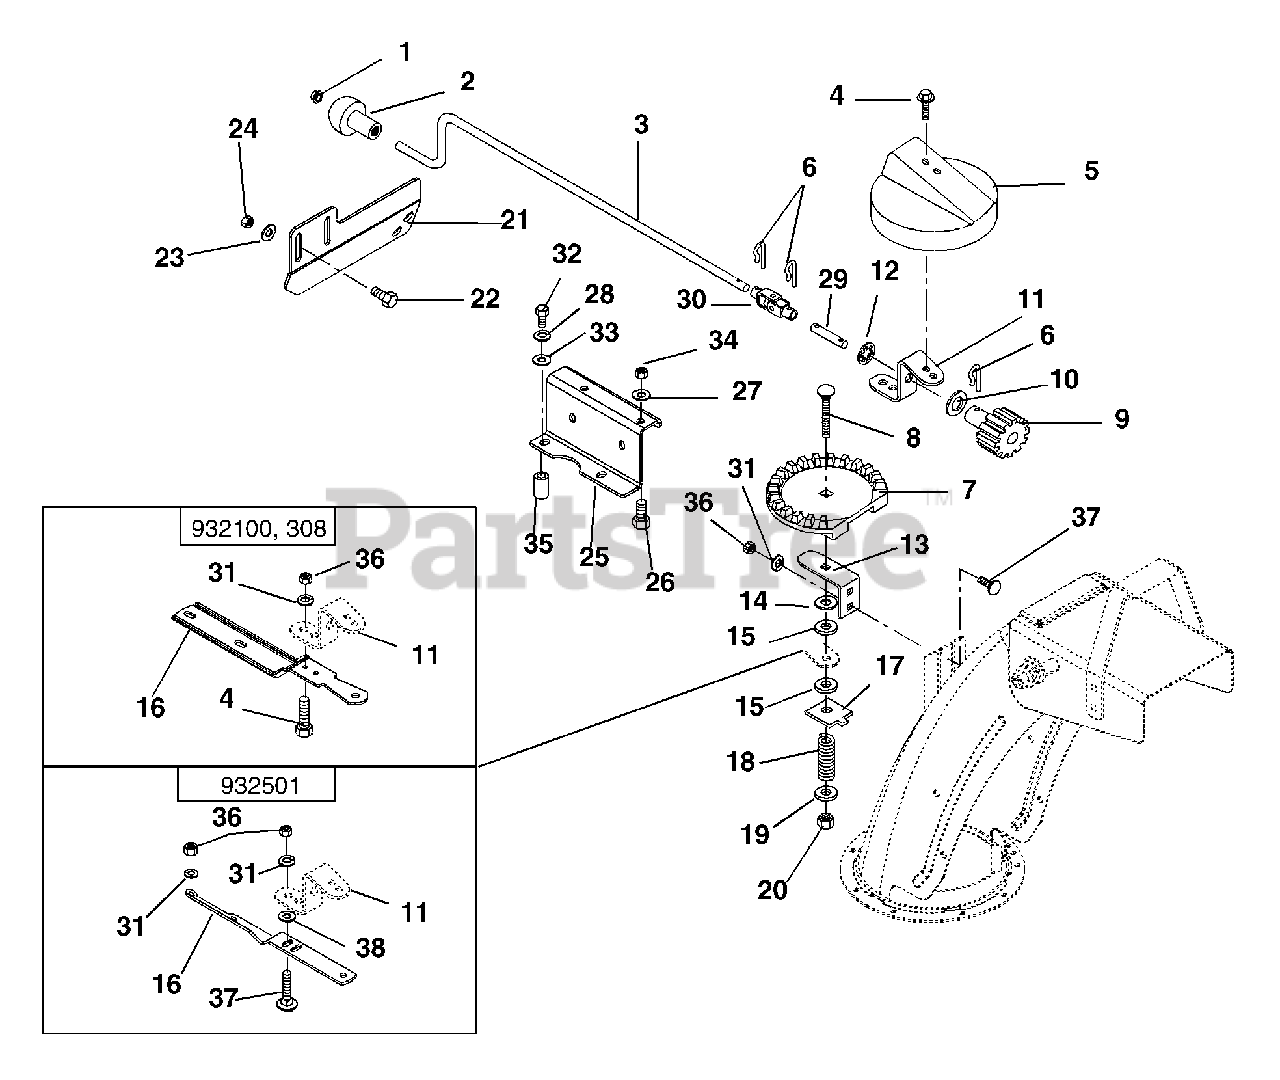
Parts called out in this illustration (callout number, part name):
1	CAP, 3/8 ROD YWZC
2	KNOB
3	CRANK, CHUTE
3	CHUTE CRANK
4	@SCR-TAP .25-20X.50 HWH TR YWZ
5	GEAR COVER
6	PIN, SPRING CLIP
7	CHUTE GEAR
8	@BLT-RDHDSQNK .38-16X2.50 G5YZ
8	@BLT-RDHDSQNK .38-16X2.25 G5YZ
9	PINION GEAR W/BRACKET
10	WSHR-FL-STL .630X1.005X.062 YZ
11	BRACKET-GEAR
12	PUSHNUT .625
13	GEAR STRAP
14	WSHR-FL-STL .380X1.50X.062 YWZ
14	@WSHR-FL-STL.563X1.38X.109YWZC
15	FRICTION WASHER
16	BRACKET, CHUTE SUPPORT
16	BRACE, CHUTE CONTROL
17	FRICTION PLATE
18	SG-COMP .187X.56X1.62
19	@WSHR-FL-STL.406X.812X.065 YWZ
20	@NUT-LK-CTR .38-16 YWZC
21	BRACKET, CHUTE CRANK SUPPORT
22	@BLT-HEX .25-20X.50 GR5 YWZC
23	@WSHR-FL-STL.312X.734X.065 YWZ
24	@NUT-LK-CTR .25-20 YWZC
25	BRACKET, ENGINE
26	@BLT-HEX .31-18X.75 GR5 YWZC
27	@WSHR-FL-STL.312X.734X.065 YWZ
28	@WSHR-LK .31X.078 REG YWZC
29	PIN, CONNECTOR
30	UNIVERSAL JOINT ASS'Y
31	@WSHR-LK .25X.062 REG YWZC
31	WSHR-LK .250X.077 HVY YWZC
32	@BLT-HEX .31-18X1.25 GR5 YWZC
33	@WSHR-FL-STL.344X.688X.065YWZC
34	@NUT-LK-CTR .31-18 YWZC
35	SPACER .322X.626X.50
36	@NUT-HEX .25-20 YWZC
37	@BLT-RDHDSQNK .25-20X.75 G5YZ
38	@WSHR-FL-STL.281X.62X.065 YWZC
